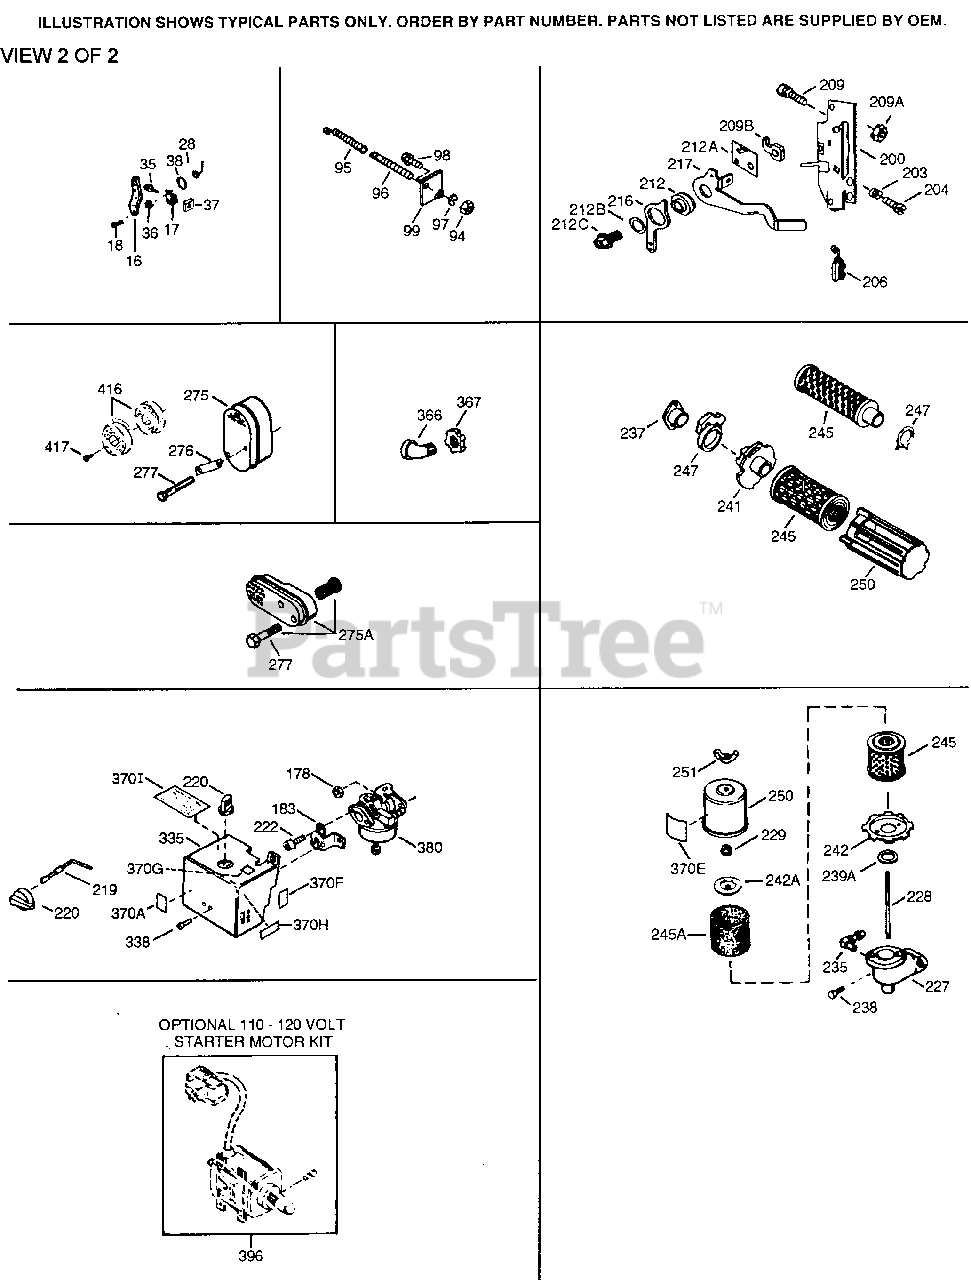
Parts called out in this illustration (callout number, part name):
16	Governor Lever
17	Governor Lever Clamp
18	Screw, 8-32 x 5/16"
28	Lock Nut, 8-32
35	Screw, 10-32 x 3/4"
36	Lock Washer #8
37	Lock Nut, 10-32
38	Retaining Ring
131	Screw, 5/16-18 x 1-1/2"
178	Nut & Lock Washer 1/4-28
200	Control Bracket Incl. 19, 203 thru 2 11
203	Compression Spring
204	Screw, 5-40 x 7/16"
238	Screw, 10-32 x 1/2"
242	Air Cleaner Base
245	Air Filter (Paper) also available in Packaged Part #740029B
250	Air Cleaner Cover
264A	Screw, 1/4-20 x 5/8"
275	Muffler
277	Screw, 1/4-20 x 1-3/4"
380	Carburetor (Incl. 184)
